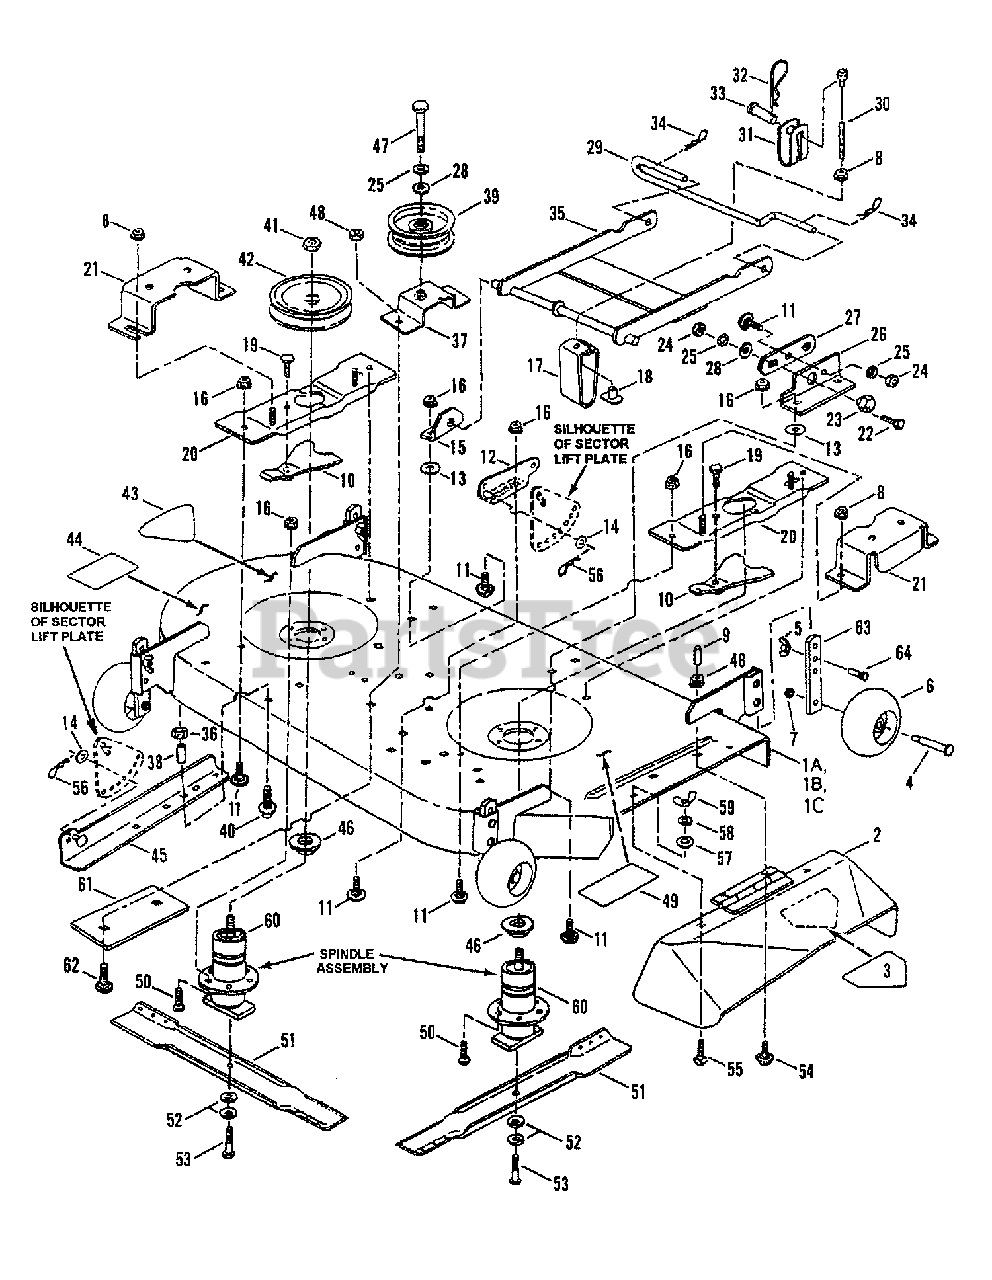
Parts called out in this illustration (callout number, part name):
1A	ASSEMBLY, 42" Cutting Deck (Includes Decal items 44 & 49)
1B	ASSEMBLY, 42" Cutting Deck (Includes Decal items 44 & 49)
1C	ASSEMBLY, 42" Cutting Deck (Includes Decal item 3 & 46720)
2	DEFLECTOR, Side Discharge (Includes item 3)
3	DECAL, Danger, Cut Finger
4	SHOULDER BOLT, 3/8-16 thread
5	WING-NUT, 3/8-16
6	WHEEL, Gage
7	NUT, 3/8-16 Hex Center Lock, GR5 or B
8	NUT, 5/16-18 Hex Flange Lock, GR5
9	VINYL CAP
10	ASSEMBLY, Spindle Lock
11	BOLT, 3/8-16 x 3/4" Short Neck Carriage, GR2
12	WELDMENT, Bracket, Sector Lift - Right Side
12A	WELDMENT, Bracket, Sector Lift - Right Side
13	WASHER, 3/8" Flat
14	WASHER, 3/8" SAE Flat
15	BRACKET, Front Hanger- Left Hand
16	NUT, 3/8-16 Hex Flange Lock
17	BRACKET, Front Lift Arm Hanger
18	TEE-NUT, 5/16-18
19	BOLT, 3/8-16 x 1" Hex Flange Lock, GR5
20	ASSEMBLY, Spindle Brace
21	GUARD, Pulley
22	SCREW, 3/8-16 x 1" Hex Head Cap, GR5
23	ADJUSTMENT RING
24	NUT, 3/8-16 Hex
25	WASHER, 3/8" Split Lock
26	BRACKET, Front (Right Side)
27	ADJUSTMENT & LINK
28	WASHER, 3/8" SAE Flat
29	PIN, Deck Hanger Improved
30	CABLE, Deck Lift 4.75
31	CLEVIS, Lift Cable
32	HAIR PIN, 3/32 x 1-1/2"
33	PIN, 3/8 x 1-1/16" Clevis
34	HAIRPIN, .148 x 2.62
35	WELDMENT, Front Lift Arm, 42
36	NUT, 3/8-16 Hex Center Lock, GR5 or B
37	ASSEMBLY, Idler Mount Bracket
38	SLEEVE, .5 O.D. x .404 I.D. x .38
39	IDLER, 4.12 Flat
40	BOLT, 3/8-16 x 1-1/2" Hex Flange Lock, GR5
41	NUT, 3/4-16 Hex Flange Jam, GR8
42	PULLEY-5.25 O.D.
43	DECAL - 42 Inch
44	DECAL, Caution (Rotating Blade)
45	WELDMENT, Sector Lift, Left Hand- 42"
46	WASHER, Spindle
47	BOLT, 3/8-16 x 1-3/4" Hex Flange Lock, GR5
48	NUT, 5/16-18 Hex Flange Lock, GR5
49	DECAL, Caution (Deflector in Place)
49B	DECAL, Chute/Deflector
50	BOLT, 3/8-16 x 3/4" Hex Flange Lock
51	BLADE, 21" Standard Lift
52	WASHER, Cone, 13/32 x 1-13/32" Diameter
53	SCREW, 3/8-24 x 1-1/4" Hex Head Cap, GR5
54	BOLT, 5/16-18 x 1" Short Neck Carriage, GR5
55	BOLT, 5/16-18 x 5/8" Short Neck Carriage, GR5
56	HAIR PIN, 3/32 x 1.5"
57	RETAINER, 5/16" Bolt
58	WASHER, 5/16" Split Lock
59	WING LOCKNUT, 5/16-18
60	ASSEMBLY, Spindle Housing, 42" Deck
61	PLATE, Support
62	SCREW, 5/16-18 x 1" Hex Head Cap, GR5
63	POST Anti-Scalp
64	SCREW, 3/8-16 x 1-1/4" Hex Head Cap, GR5
